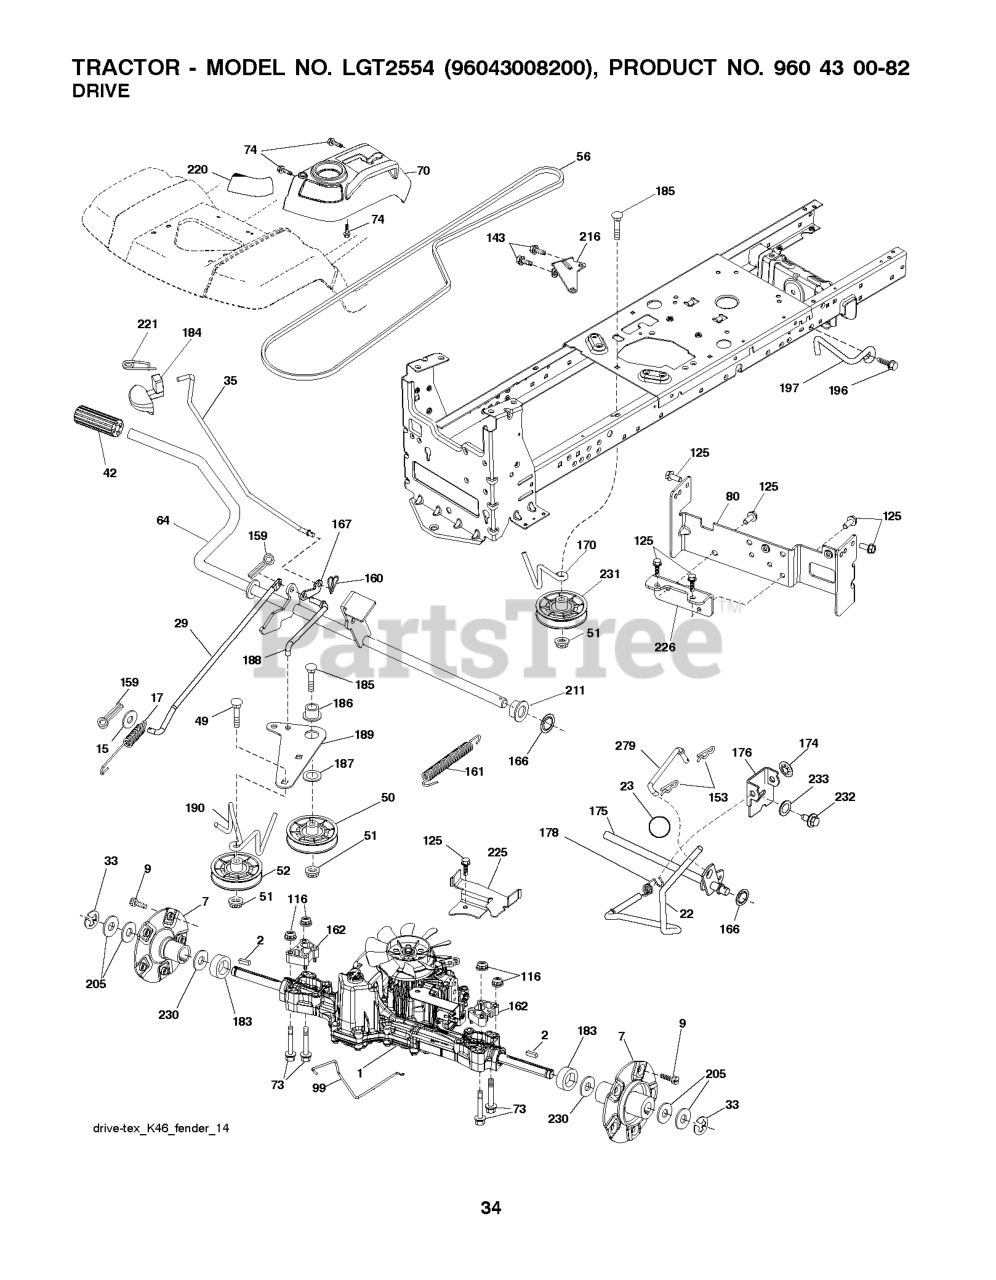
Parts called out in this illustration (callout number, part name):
1	TRANSAXLE(K46AW)22"FS
2	KEY.SQUARE.187X2.500
7	HUB.ASM.WHEEL.REAR.22"
9	HUB BOLT
15	WASHER
17	SPRING.BRAKE.K46.GREEN
22	ROD.SHIFT.FENDER.STGT.
23	KNOB.DELUXE.(PISTOL.GRIP).BLAC
29	ROD.BRAKE.K46
35	ROD.BRAKE.PARKING.GT.H
42	PEDAL COVER T
50	IDLER.FLAT.910.OFFSET
51	NUT LOCK FLG 3/8-16 UNC
52	IDLER.V-GROOVE.910.OFFSET
56	V-BELT.MOWER.92.40.42/K46
64	SHAFT.ASM.PEDAL.BRAKE.
70	RP CONSOLE.ASM.HYDO.HUSQ.
73	BOLT.HEX.FLNG.5/16-18X3.75
74	SCREW.HI-LO.CONSOLE
80	STRAP TORQUE
99	ROD.SPRING.BYPASS.K46.TEX.GT
116	NUT LOCK HEX FLANGE 5/16-18
125	SCREW
143	Screw 5/16-18 x 1/2 Hex, Self Tapping 5/16-18 x 1/2
153	RETAINER M
159	COTTER PIN
160	RETAINER CLIP
161	SPRING, RETURN LT
162	SPACER.TRANSAXLE.18&22
166	NUT.PUSH.625.2006
167	LATCH.BRAKE.SPRING
170	KEEPER.CENTER SPAN.1.688
174	NUT.PUSH.500.2006
175	SHAFT ASM SHIFT
176	ARM.CLEVIS.ROD.SHIFT
178	SPRING.SHIFT.GT2006
183	SPACER.SPLIT.800X.350
184	HANDLE.PARKG.BRK.HUSQ X667
186	SPACER.RETAINER
187	WASHER 12/32X2X10GA
188	RP.LINK.CLUTCH.GROUND.DRIVE
189	BELLCRANK.GROUND.DRIVE.TEX.
190	KEEPER.BELLCRANK.DRIVE
196	SCREW 3/8-16X1
197	BRKT.ANIT-ROTATION.CLUTCH
211	BUSHING.SHAFT.BRAKE.HAND
216	BRACKET.PULLEY.IDLER.W/TEX
220	REFLECTOR.RH.TEX GT
221	RETAINER.SPRING.CLIP.H
225	KEEPER.BELT.TRANSAXLE.K46
226	BRKT.MOUNT.TORQUE.K46.
230	WASHER.HARDENED
231	IDLER.V-GROOVE.1.688.OFFSET
232	BOLT FIN HEX 7/16-14 X 1
233	WASHER SERRATED
279	LINK.SHIFT.T/A.K46.FEND.TX
